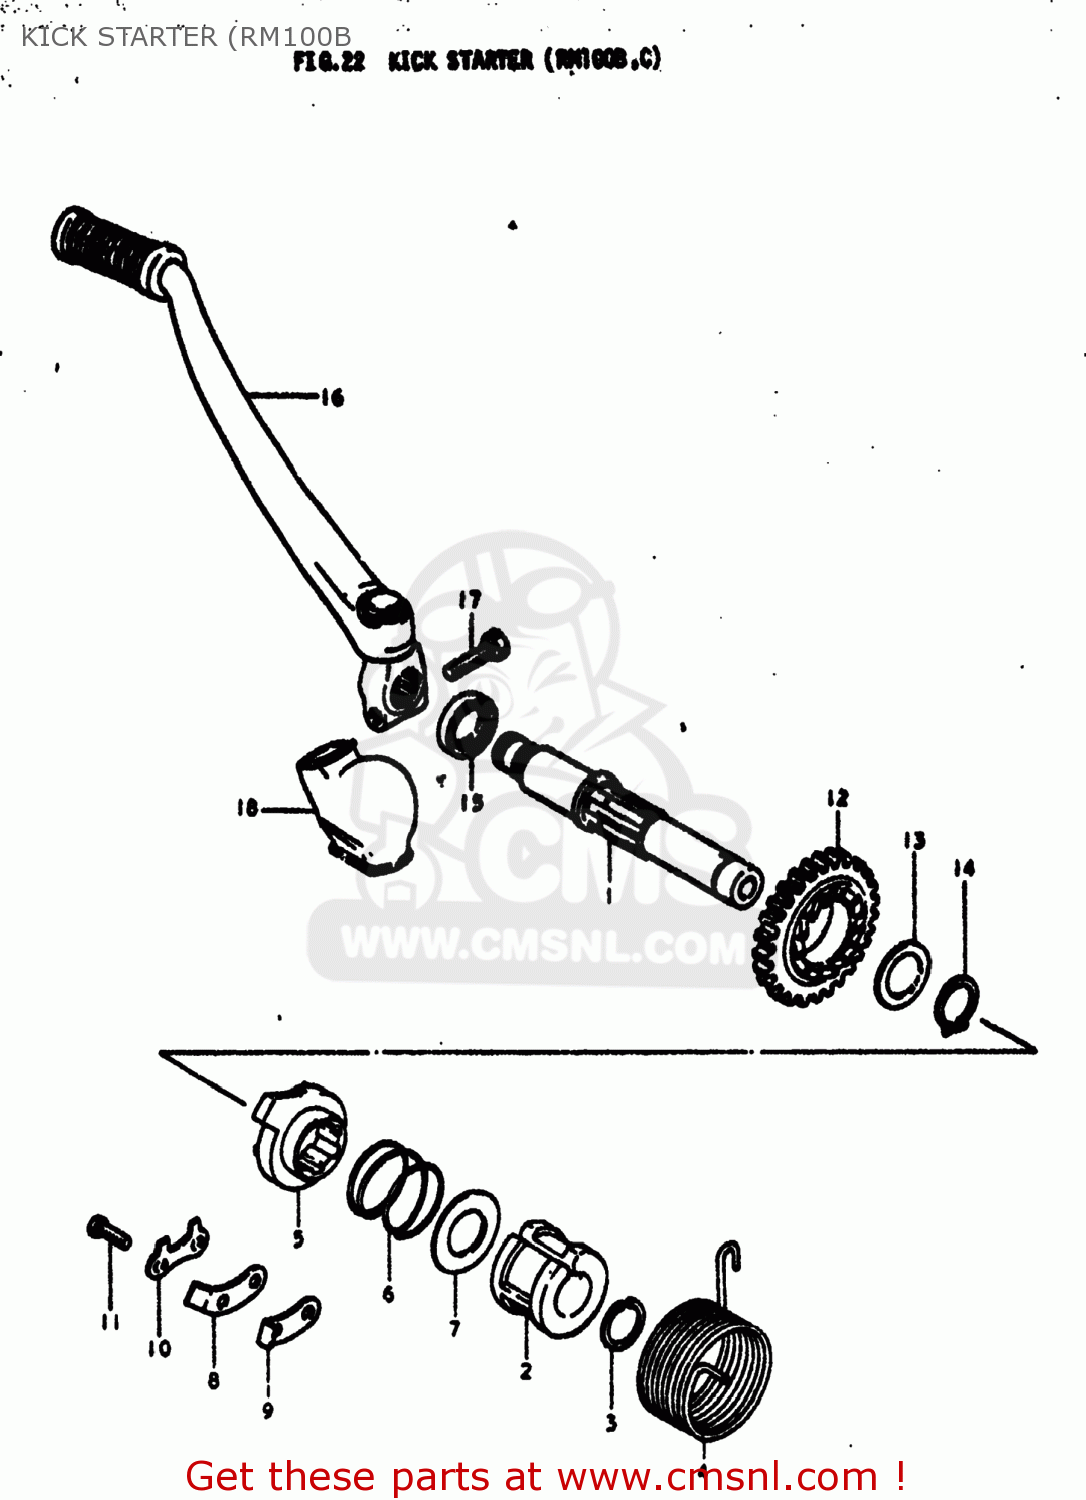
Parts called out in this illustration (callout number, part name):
1	SHAFT,KICK STARTER
2	GUIDE,KICK STARTER SFT SPRING
3	CIRCLIP
4	SPRING
5	STARTER,KICK
6	SPRING
7	WASHER
8	GUIDE,KICK STARTER
9	STOPPER,KICK STARTER
10	WASHER
11	BOLT
12	GEAR,KICK STARTER DRIVE
13	SHIM
14	CIRCLIP
15	SEAL,OIL(16X24X5)
16	LEVER ASSEMBLY,KICK STARTER
17	BOLT
18	COVER,KICK LEVER JOINT
